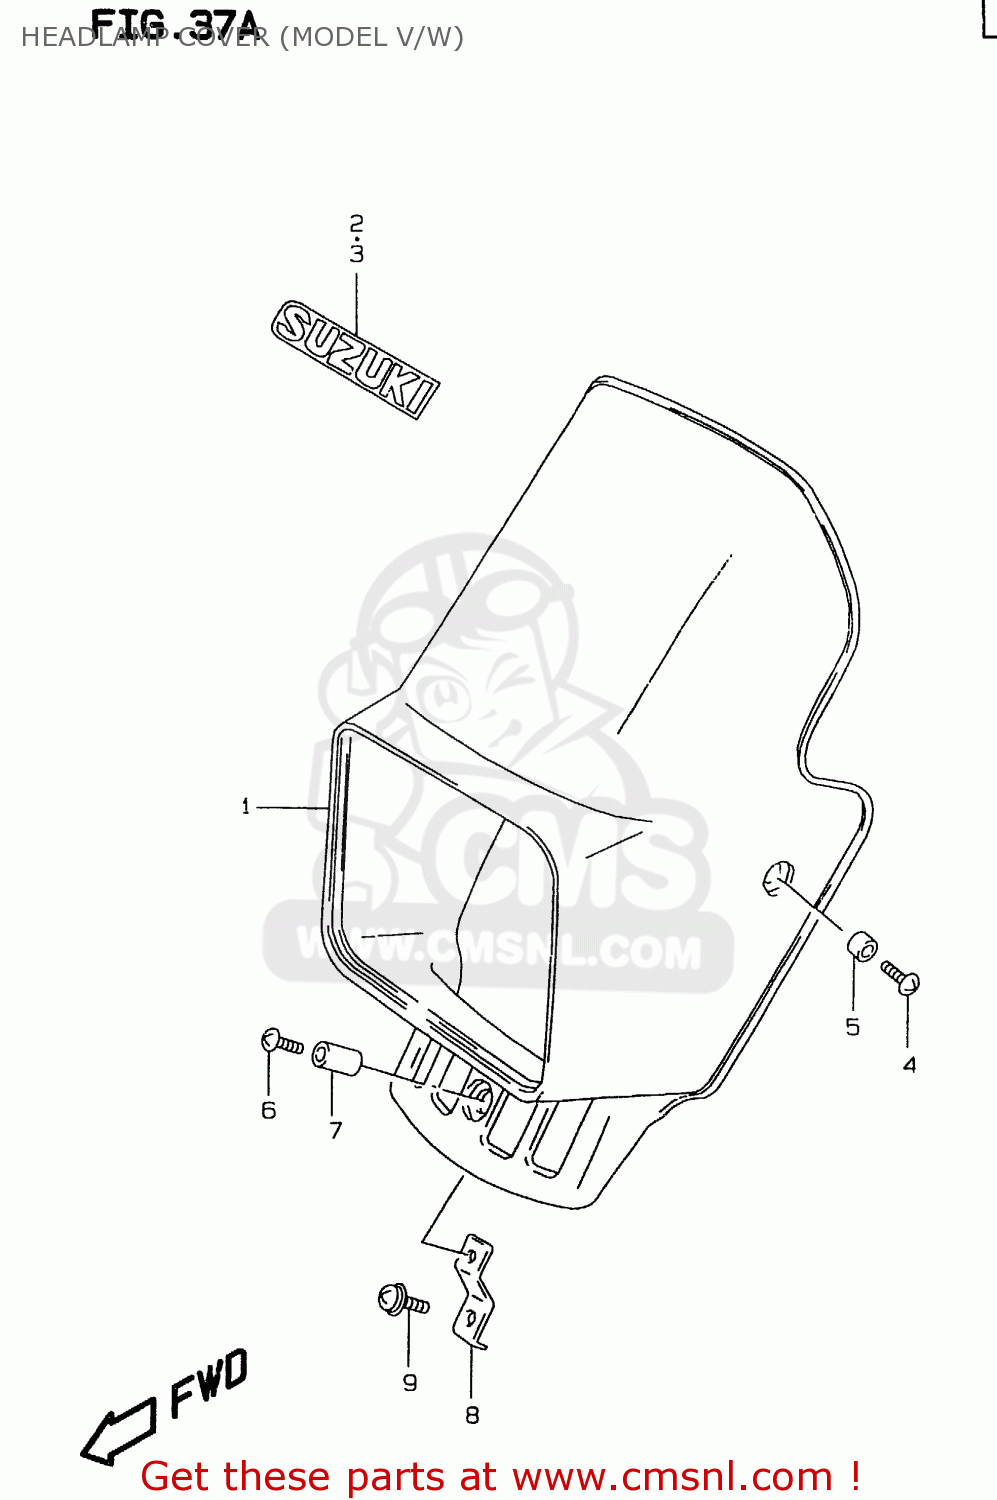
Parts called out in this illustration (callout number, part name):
1	COVER,HEADLAMP
2	EMBLEM,SUZUKI
3	EMBLEM
4	SCREW 6X12
5	SPACER(6.1X8X3.5)
6	SCREW
7	SPACER(6.1X8X12)
8	PLATE,HEADLAMP COVER
9	SCREW
